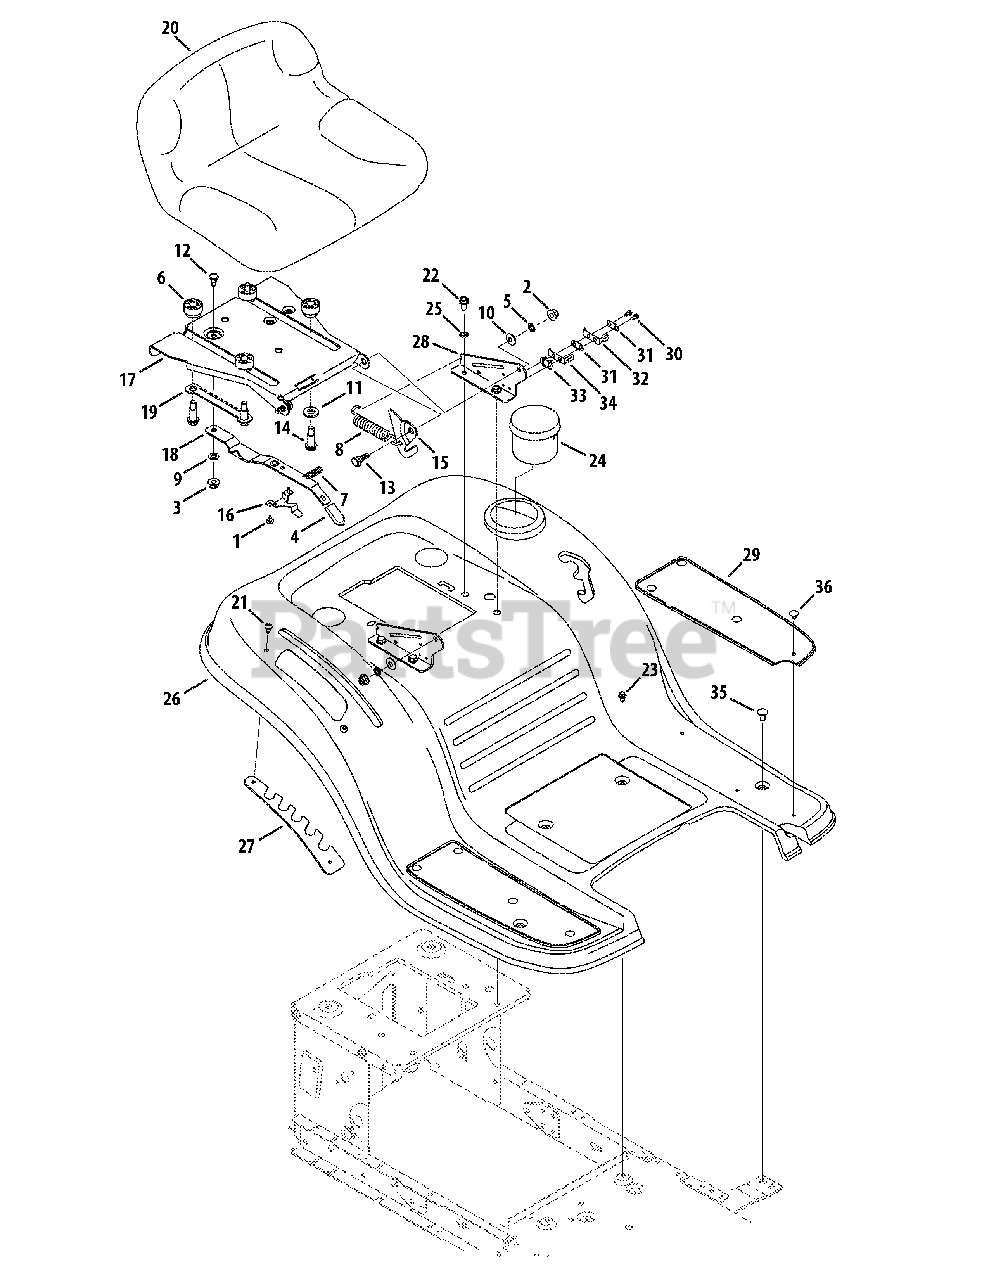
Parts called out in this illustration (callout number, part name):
1	Screw, #10-16 x .375
2	Flange Lock Nut, 5/16-18
3	Flange Lock Nut, 1/4-20
4	Seat Adjustment Grip
5	Speed Nut
6	Seat Adjustment Spacer
7	Compression Spring, .41 x 1.50
8	Extension Spring
9	Flat Washer, .344 x .62 x .033
10	Flat Washer, .340 x .872 x .060
11	Flat Washer, .531 x .062 x .134
12	Shoulder Screw, .34 x .285: 1/4-20
13	Shoulder Screw, 5/16-18 x .437 x .268
14	Shoulder Bolt, .50 x .925: 3/8-16
15	Lift Seat Bracket
16	Seat Adjustment Stop Bracket
17	Seat Pivot Bracket
18	Seat Adjustment Lever
19	Seat Adjustment Selector
20	Low Back Seat
21	Screw, 1/4-20 x .500
22	Screw, 5/16-18 x .750
23	Screw Pan Torx Head, 1/4-20 x .500
24	Cup Holder
25	Lock Washer, 5/16
26	Fender
27	Lift Adjuster Bracket
28	Seat Mounting Bracket
29	Rubber Foot Pad, LH
29	Rubber Foot Pad, RH
30	Screw, 8-18 x .500
31	Insulator Plate
32	Outer Seat Spring
33	Insulator Boss Plate
34	Inner Seat Spring
35	Carriage Screw, .62: 1/4-20
36	Ratchet Clip, .250 x .500
